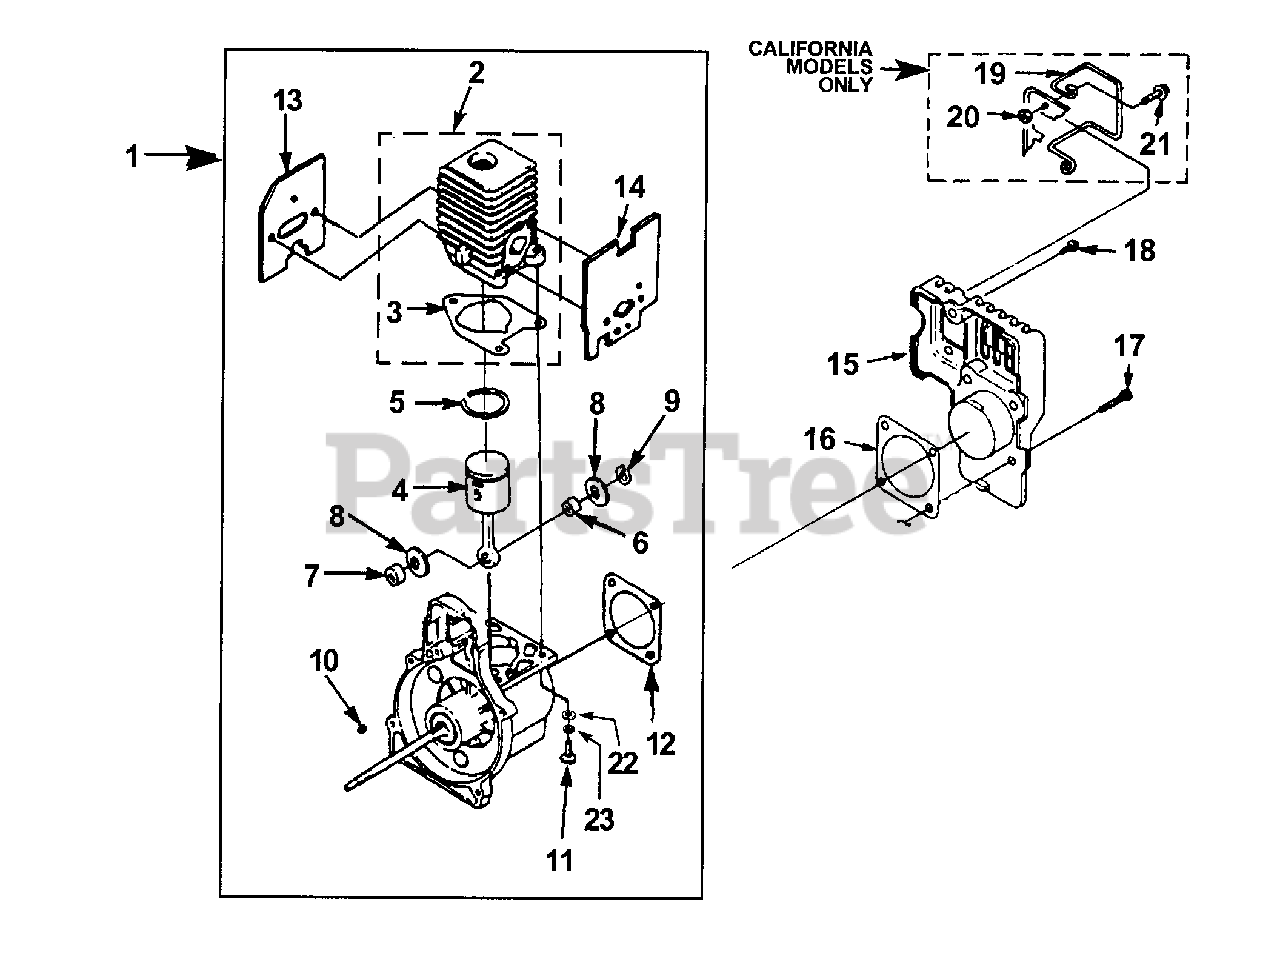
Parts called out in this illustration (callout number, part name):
1	Short Block
2	Cylinder & Gasket
3	Cylinder Gasket
4	Piston & Rod
5	Piston Ring
6	Needle Bearing
8	Thrust Washer
9	Retaining Ring
10	Woodruff Key
11	Screw, Sems (12-24 x 3/4")
12	Crankcase Gasket
13	Muffler Gasket
14	Heat Dam Gasket
15	Crankcase Cover
16	Crankcase Gasket
17	Screw-Taptite (10-24 x .910)
18	Screw-Plastite (10 x 1/2")
19	Wire Guard Kit
20	Nut (10-24)`
21	Screw-Sems Hex Hd. (10-24 x 1/2")
22	Washer, Flat
23	Washer, Lock
